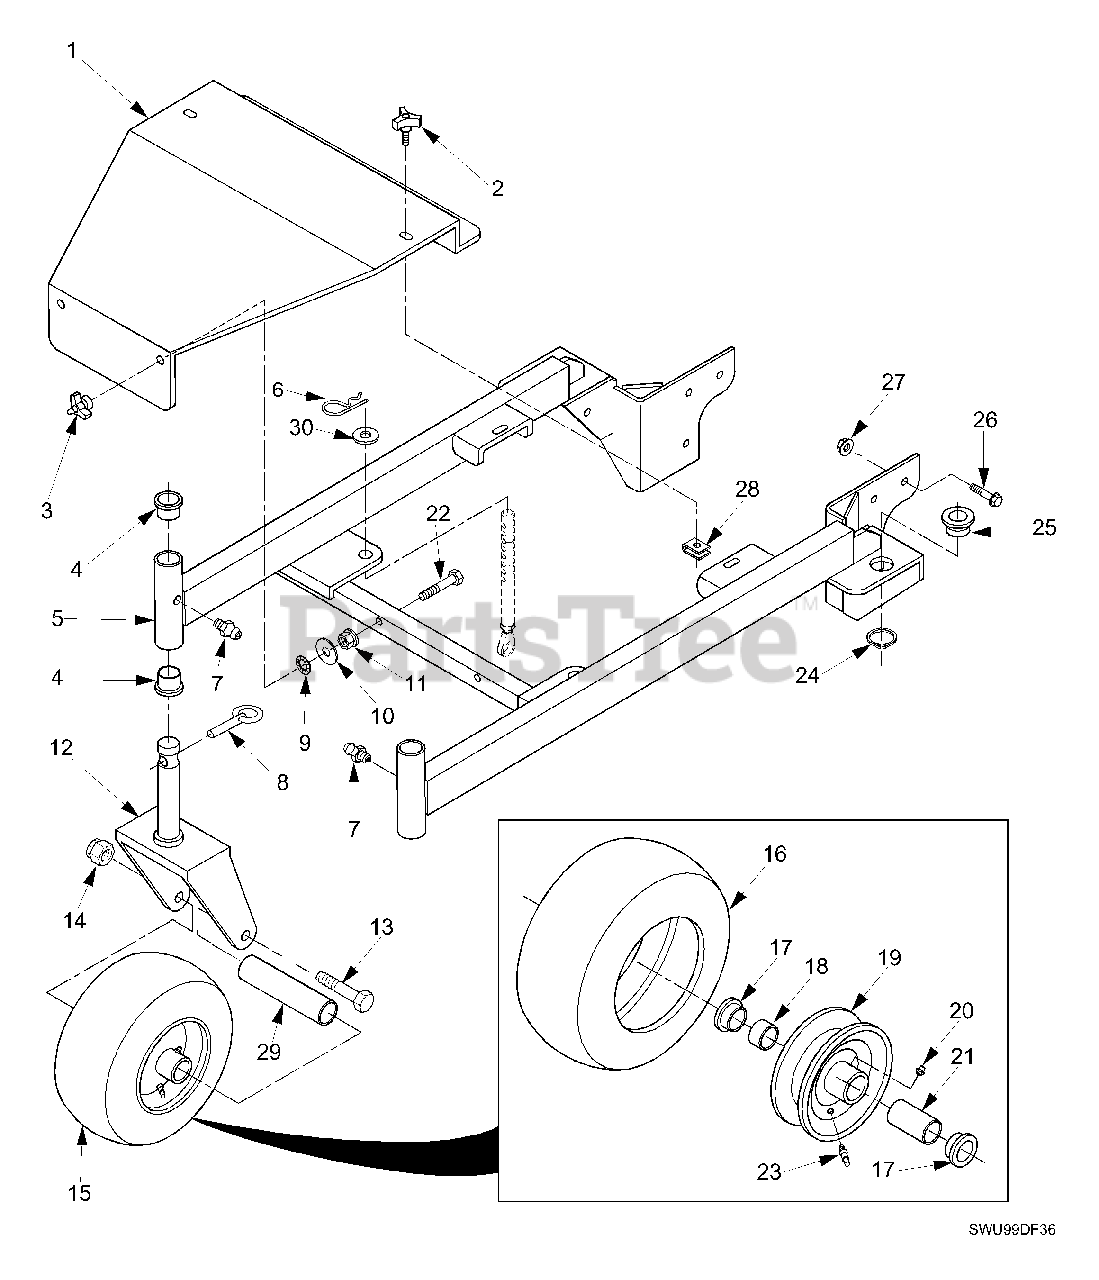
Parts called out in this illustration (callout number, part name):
1	Belt Cover With Decal
2	Knob With Stud
3	Knob, Deck Cover Mounting
4	Bushing, Caster
5	Frame Weldment, Deck Mounting - 36"
6	Hair Pin Cotter, .177 x 3.25"
7	Grease Fitting Str. 1/4-28 Self Tap
8	Quick Pin,.438 Dia
9	Nut, Push-On - 3/8 Thd.
10	Flatwasher, 3/8 - (.391 x .938 x .105)
11	Nut, 3/8-16 Serrated Flange Hex Head
12	Yoke, Caster Wheel
13	Capscrew, Hex Head 1/2-13 x 6.50"
14	Locknut, 1/2-13 Elastic Stop
15	Wheel Assembly, Caster
16	Tire, 11 x 4.00-5
17	Retainer
18	Roller Bearing
19	Rim, 5.0 x 2.75 With Zerk & Valve
20	Grease Fitting Str.1/4-28
21	Roller Bearing .625 x 3.25"
22	Capscrew, Hex Head 3/8-16 x 2.25"
23	Tire Valve, Purchase Locally
24	Retaining Ring 1.50 Ext.
25	Bushing, Deck Adjustment Pin
26	Capscrew, Hex Head 7/16-14 x 1.0"
27	Nut, 7/16-14 Serrated Flange Hex
28	U-Nut, 3/8-16
29	Sleeve, Caster Wheel
30	Flatwasher, 5/8 - (.688 x 1.75 x .134)
